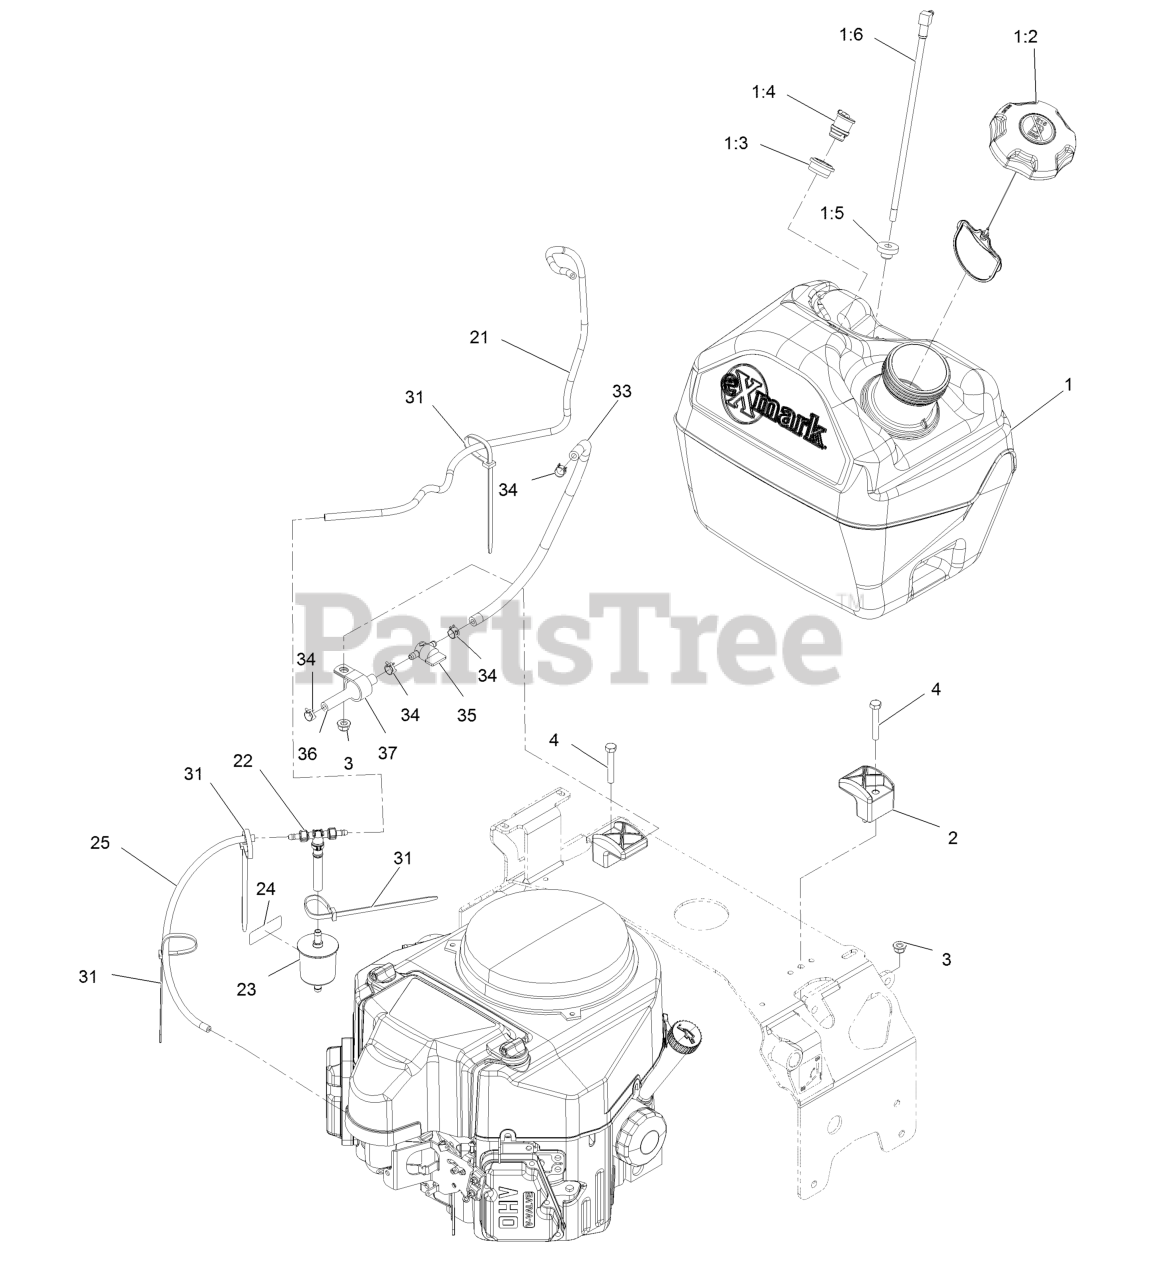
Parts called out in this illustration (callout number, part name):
1	ASM, Fuel Tank 5 Gal
1:2	Cap-Fuel, Ratcheting
1:3	Grommet
1:4	Valve-Vent, Fuel
1:5	Bushing
1:6	Fitting-Fuel (W/Line And Screen)
3	Nut-Nyloc 5/16-18 Flg
4	Screw-HH 5/16-18 X 2
21	Hose, Emissions
22	Tee And Check
23	Filter-Fuel
24	Decal-Filter, Emissions
25	Hose-Fuel
31	Tie-Cable 7 15/16 (Large)
33	Hose-Fuel
34	Clamp-Hose
35	Valve-Fuel
36	Hose-Fuel
37	Clip-Loom
